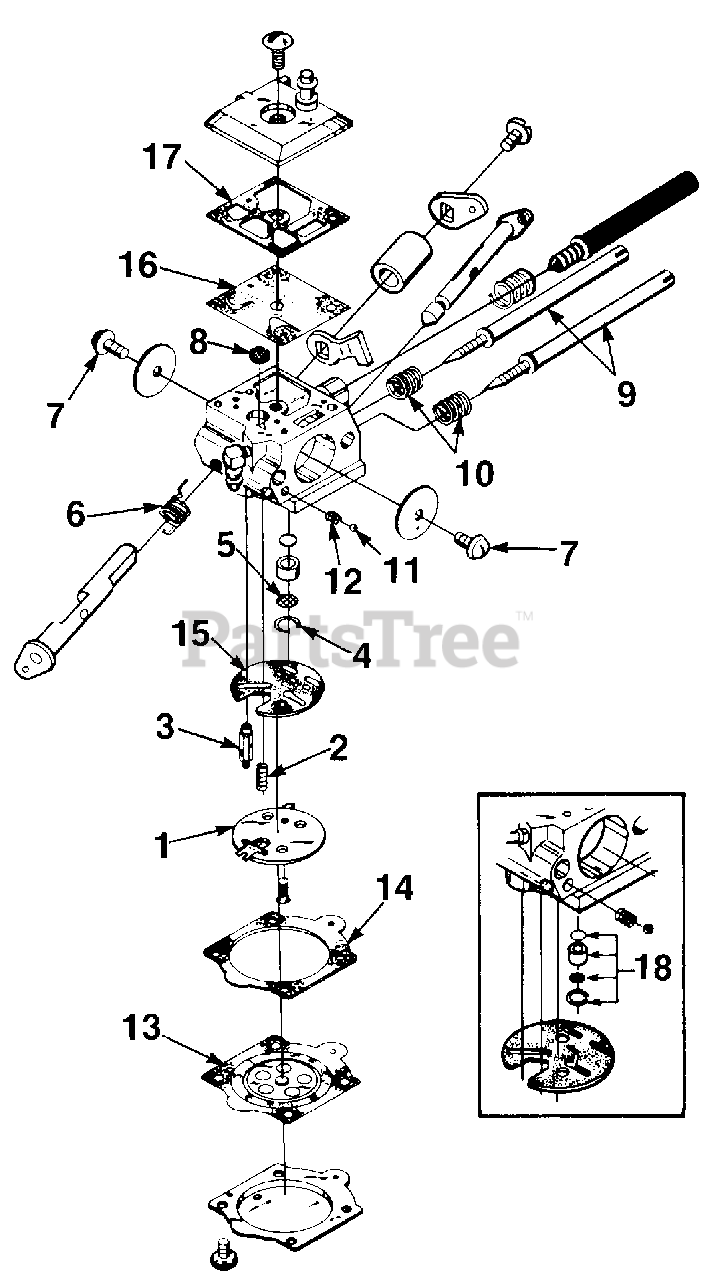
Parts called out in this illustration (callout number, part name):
1	Repair Kit
2	Repair Kit
3	Repair Kit
4	Repair Kit
5	Repair Kit
6	Repair Kit
7	Repair Kit
8	Repair Kit
9	Repair Kit
10	Repair Kit
11	Repair Kit
12	Repair Kit
13	Repair Kit
14	Repair Kit
15	Repair Kit
16	Repair Kit
17	Repair Kit
18	Check Valve Repair Kit
